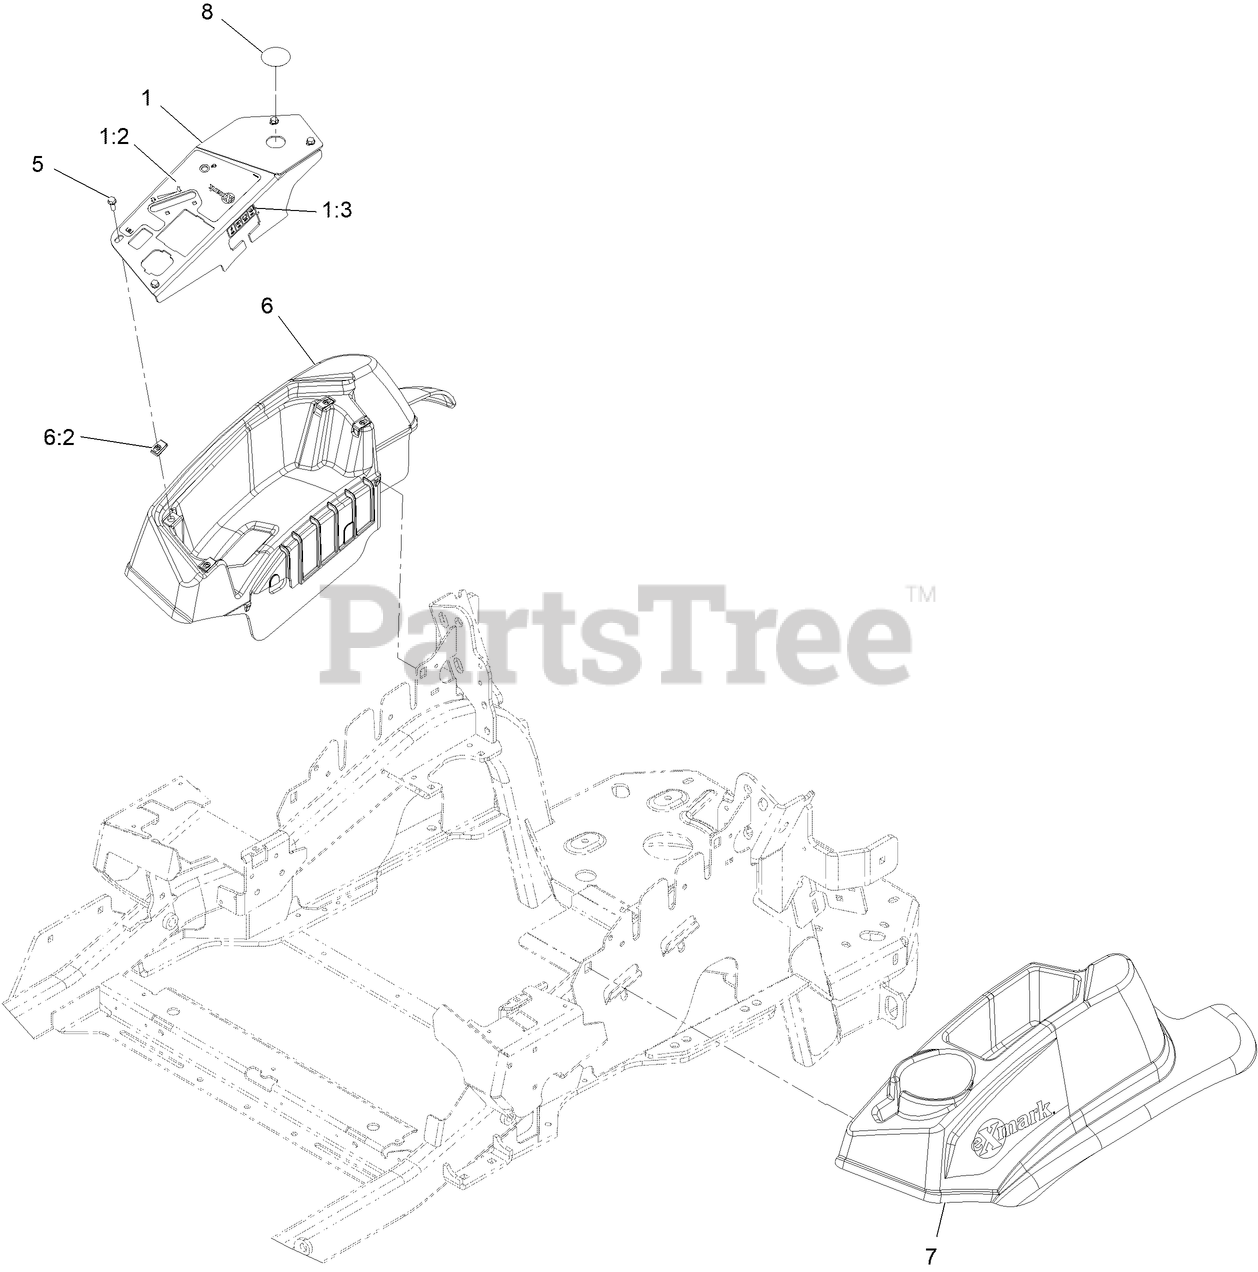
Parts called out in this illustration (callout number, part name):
1	ASM,CONTROL PANEL W/DECAL
1:2	DECAL-CONTROL PANEL EFI
1:3	DECAL-FUSES
5	SCREW-HWH
6	ASM - RH Console
7	Console-LH
8	Decal-Cover 12V
